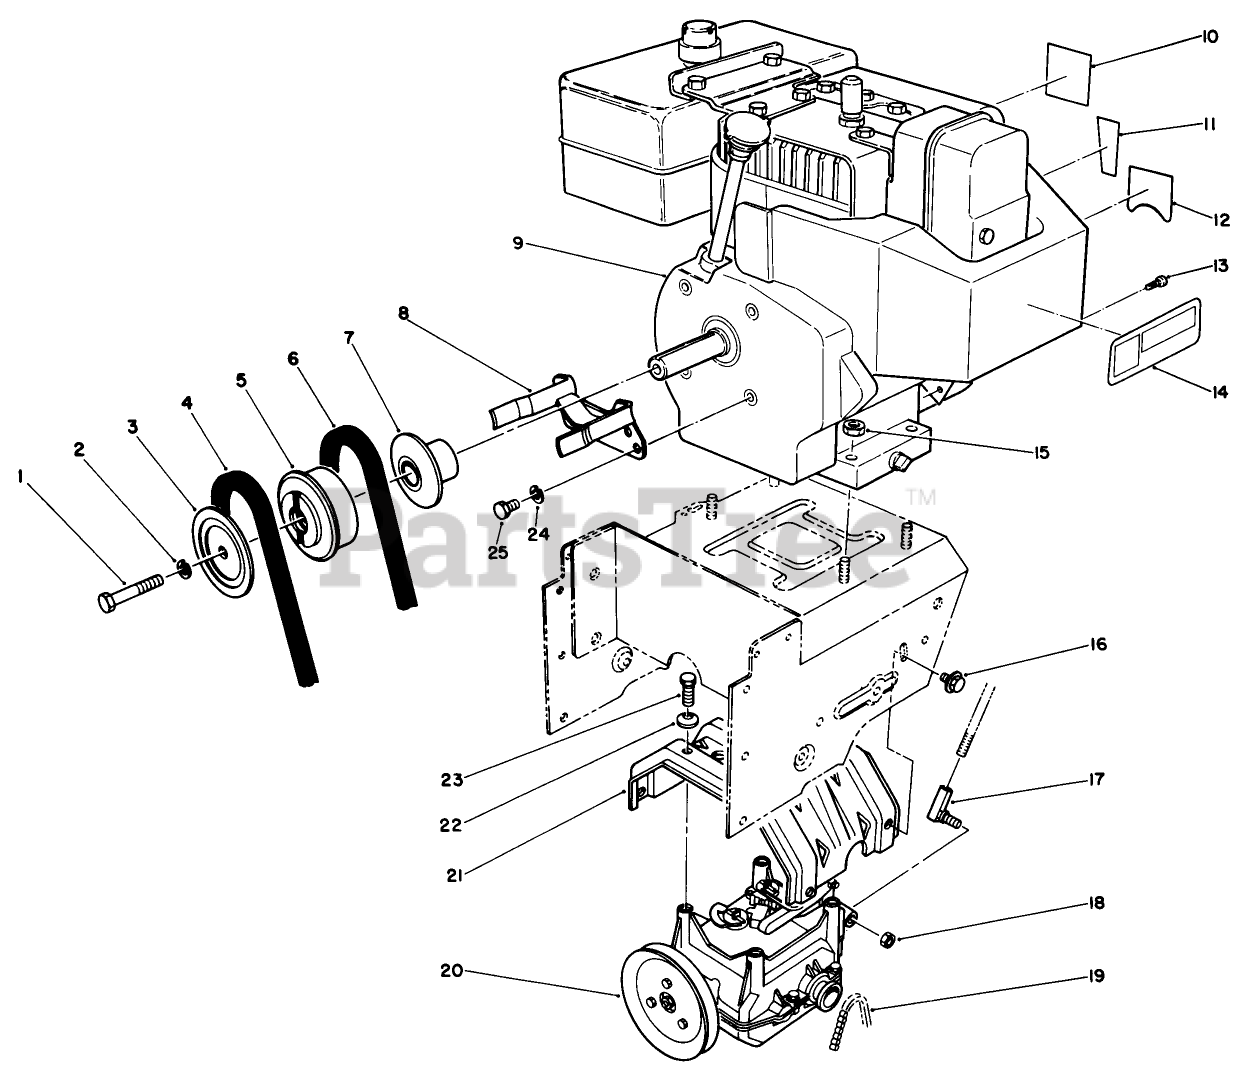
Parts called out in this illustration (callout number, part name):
1	SCREW-HH
2	WASHER-LOCK
3	SHEAVE-HALF, IMPELLER
4	V-BELT
5	PULLEY-ENGINE, CENTER
6	V-BELT-TRACTION
7	SHEAVE-HALF, TRACTION
8	Guide-Belt
10	DECAL-PRIMER
11	DECAL-THROTTLE
12	DECAL-CHOKE
13	SCREW-HWH
14	DECAL-HOT SURFACE, WARNING
15	NUT-HF
16	SCREW-HHF
17	JOINT-BALL
18	NUT-LOCK, NI
19	CHAIN
20	TRACTION GEARCASE ASM
21	Frame-Transmission
22	WASHER-SPRING
23	SCREW-HWHTF
24	WASHER-LOCK
25	SCREW-HH
